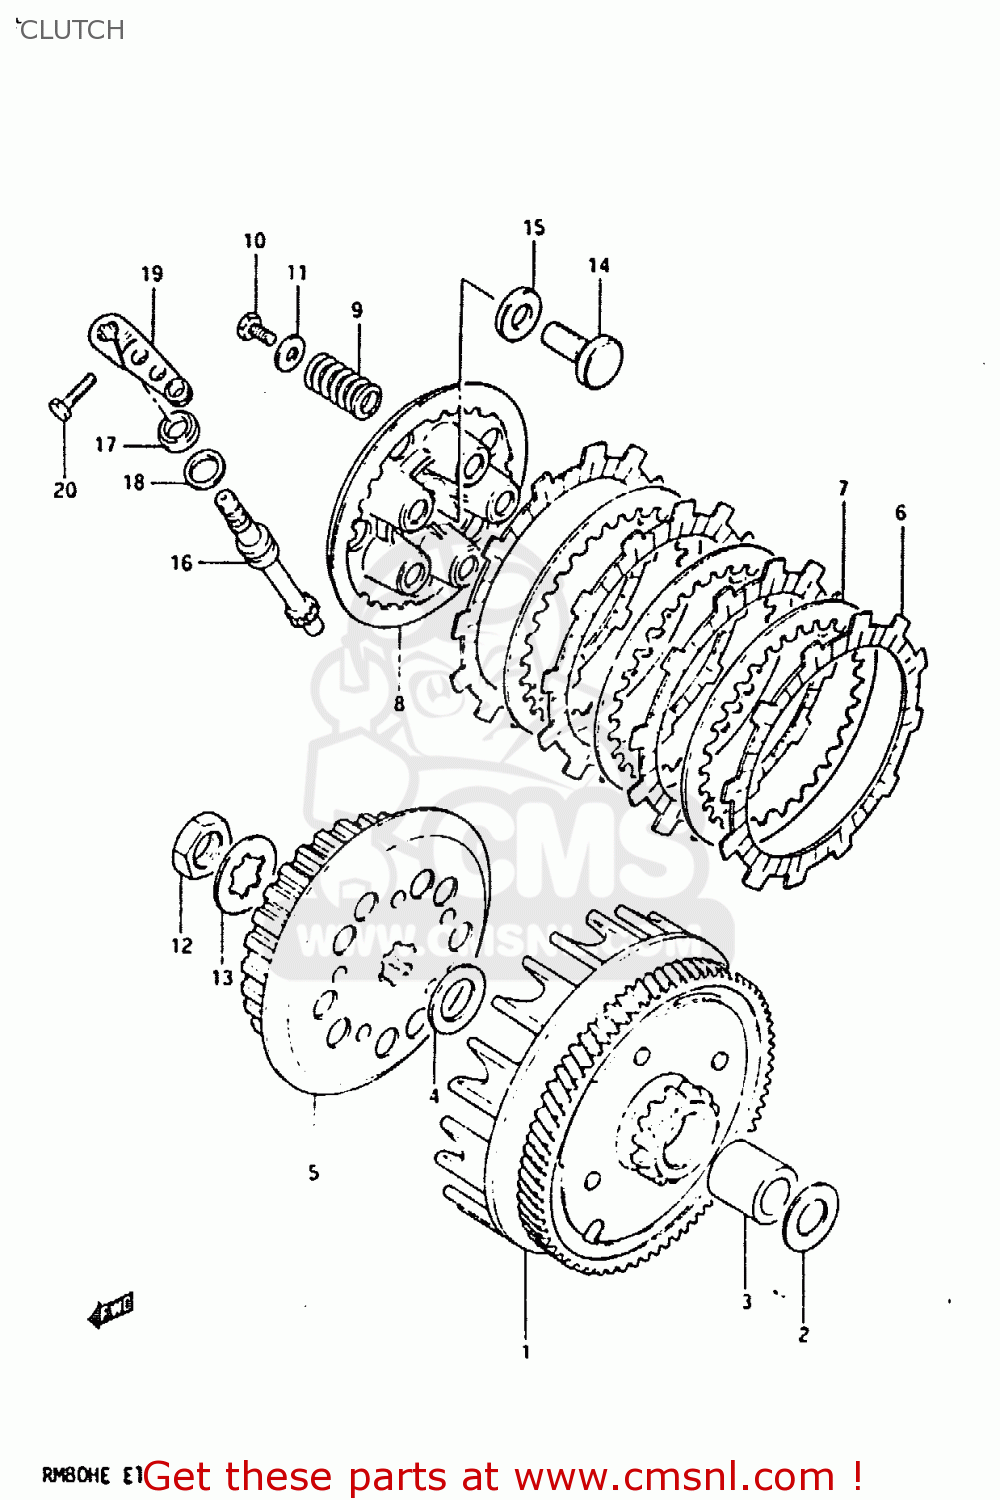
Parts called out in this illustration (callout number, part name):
1	GEAR ASSEMBLY,PRIMARY DRIVE
2	WASHER,THRUST
3	SPACER(17X22X28.5)
4	WASHER
5	HUB,CLUTCH SLEEVE
6	PLATE,CLUTCH DRIVE
7	PLATE,CLUTCH DRIVEN (NAS)
8	DISC,CLUTCH PRESSURE
9	SPRING
10	BOLT(5X16)
11	WASHER (5.5X16X1.2)
12	NUT
13	WASHER,LOCK
14	RACK,CLUTCH RELEASE
15	BEARING(10X22X2.8)
16	PINION,CLUTCH RELEASE
17	SEAL,OIL(10X17X5)
18	WASHER (12X17X1)
19	ARM,CLUTCH RELEASE
20	BOLT, UPPER
